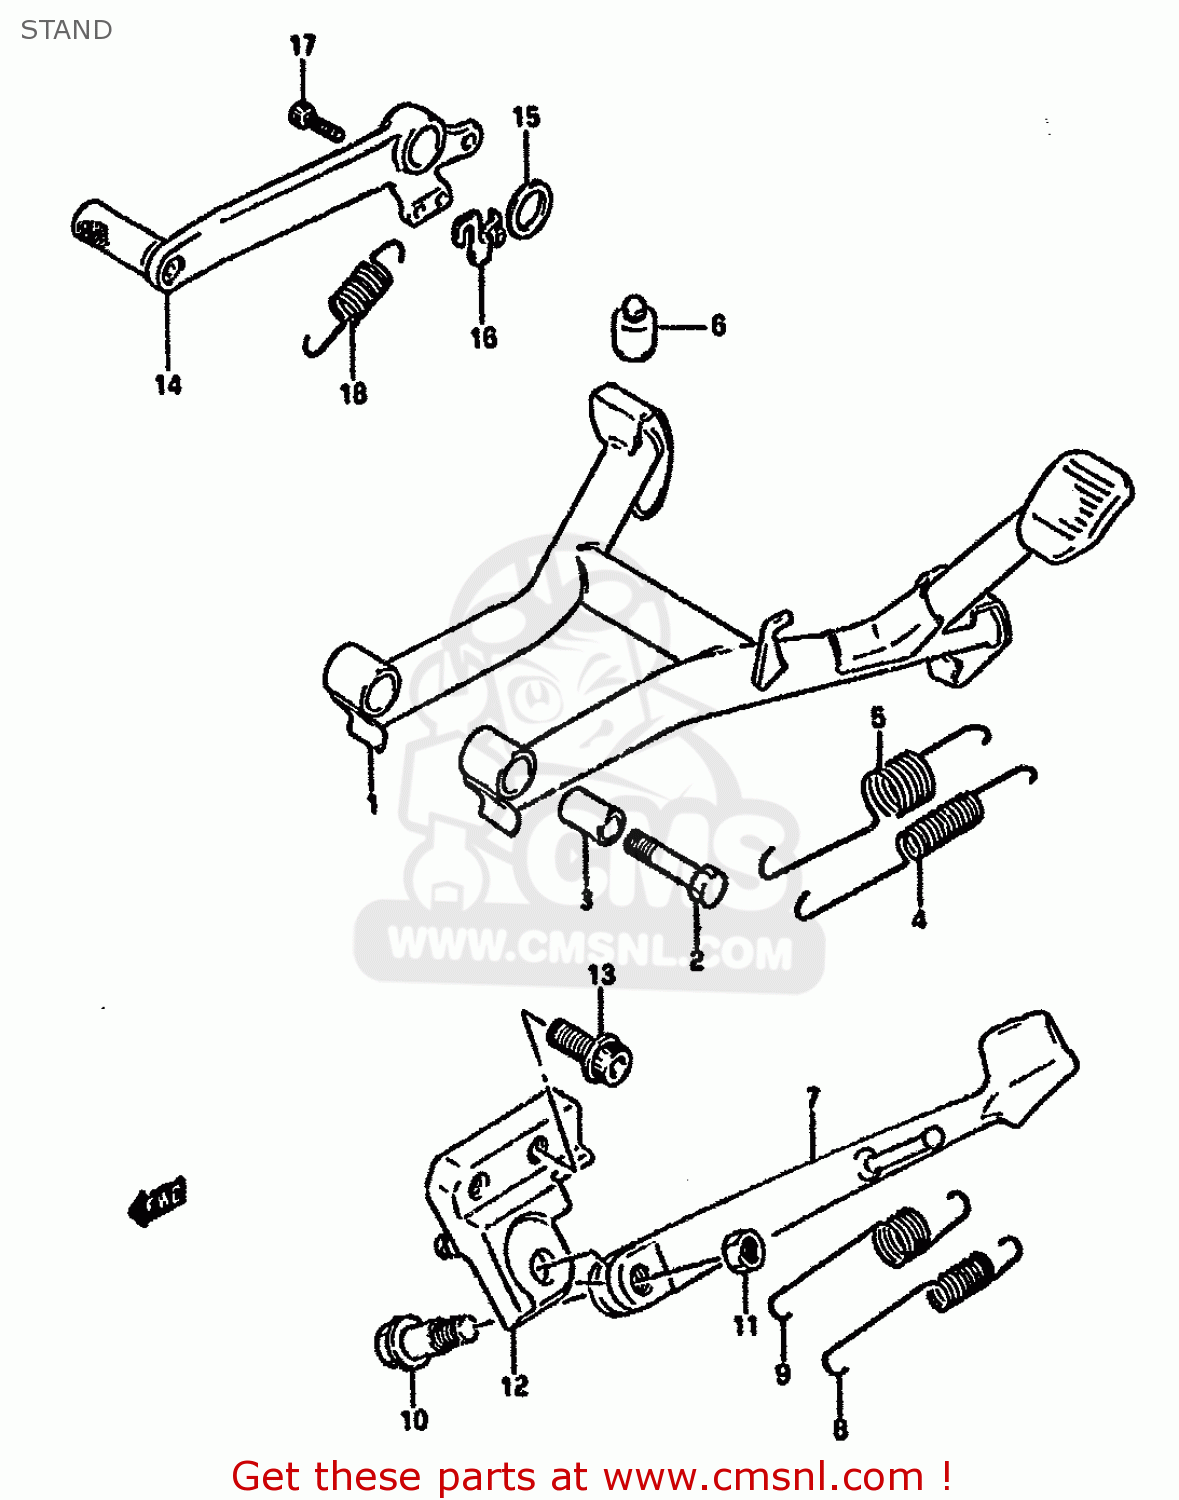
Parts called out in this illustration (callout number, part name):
1	STAND,CENTER
2	BOLT(10X43)
3	SPACER(10X16X25.5)
4	SPRING
5	SPRING OUTER
6	CUSHION
7	STAND,SIDE
8	SPRING
9	SPRING
10	BOLT(10X30)
11	NUT
12	BRACKET,SIDE STAND
13	BOLT
14	PEDAL,BRAKE
15	WASHER(18.2X27X1)
16	BRACKET,STOP LAMP SWITCH SPR
17	BOLT
18	SPRING
